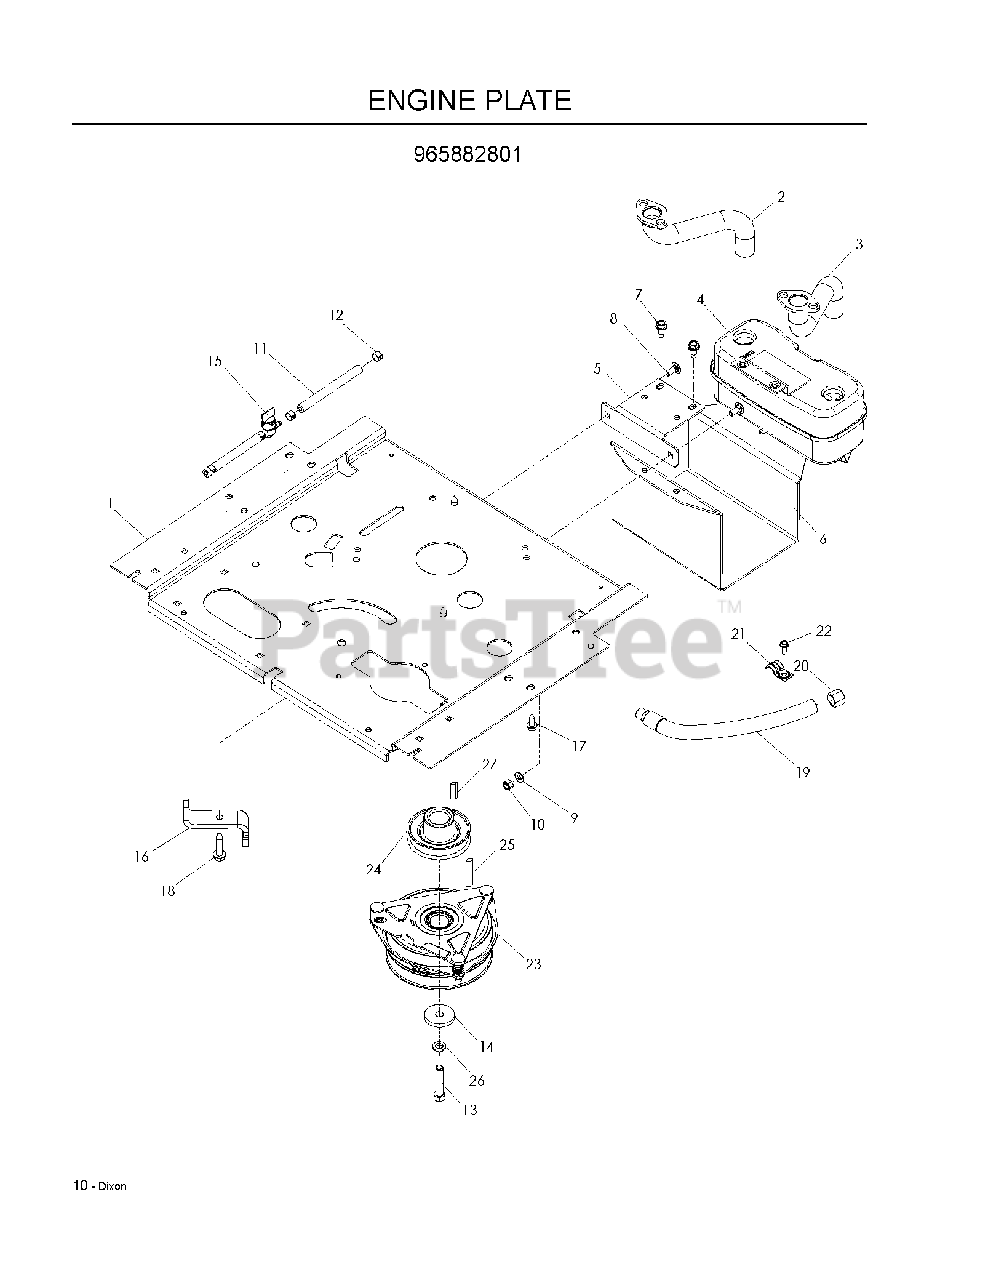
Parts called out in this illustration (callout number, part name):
1	PLATE, ENGINE, BLACK
2	RP.PIPE-EXHAUST LH
3	RP.PIPE-EXHAUST RH
4	MUFFLER ASM TWIN
5	BRACKET, MUFFLER, BLACK
6	GUARD, MUFFLER, BLACK
7	BOLT 5/16-18 X 3/4
8	BOLT 5/16C X 3/4" CARRIAGE
9	FLAT WASHER 5/16 SAE
10	NUT 5/16 NYLOC
11	FUEL LINE 5"
12	HOSE CLAMP
13	HCS 7/16-20 X 2 G8 ZN
14	SPINDLE WASHER
15	FUEL VALVE
16	STOP, CLUTCH, OGURA, BLK
17	HHFS 3/8-16 X 1.0 THD FORMING
18	BOLT 3/8-16 X 1 1/2 ZINC CLEAR
19	OIL DRAIN HOSE
20	DRAIN CAP
22	SCREW 1/4 X 5/8
23	CLUTCH, 150 FT/LBS
24	PULLEY, 4.5"
25	KEY 1/4 SQ X 2
26	WASHER 7/16 LOCK
27	KEY 1/4 SQ X 1.0
